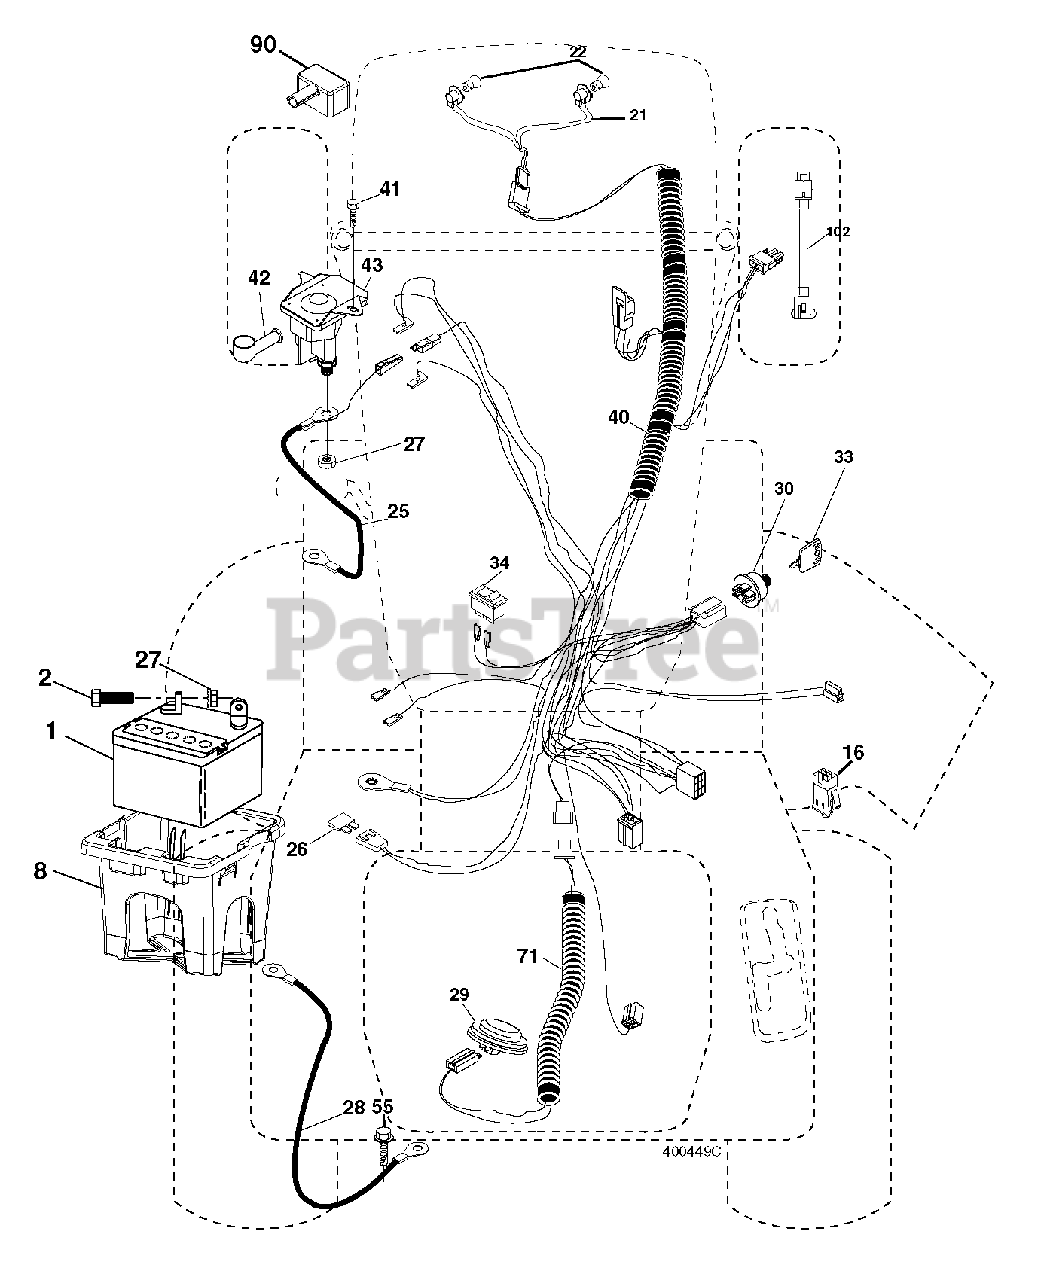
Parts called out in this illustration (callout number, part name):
1	BATTERY 12V .35 AMP
8	BOX.BATTERY.MNT.REAR.L
16	SWITCH INTERLOOK PUSH-IN
21	HARNESS ASSY LIGHT
22	LIGHTBULB
25	CABLE.STARTER.6GA.RED.
26	FUSE 20AMP
27	NUT
28	CABLE.BLACK.18"REAR.BA
29	SWITCH.SEAT.DELTA.OPC.
30	SWITCH.IGN.DELTA.W.LGH.ROS
33	KEY MLD GEN DELTA
34	SWITCH LT
40	HARNESS.IGN.CHASS.TEX.REAR.BAT
41	SCREW
42	TERMINAL COVER
43	SOLENOID.W/BRASS.PLUNG
55	SCREW 5/16"
71	HARNESS IGN. DASH
90	COVER, TERMINAL BATTERY
102	HARNESS PIGTAIL PCH TEX ROS
